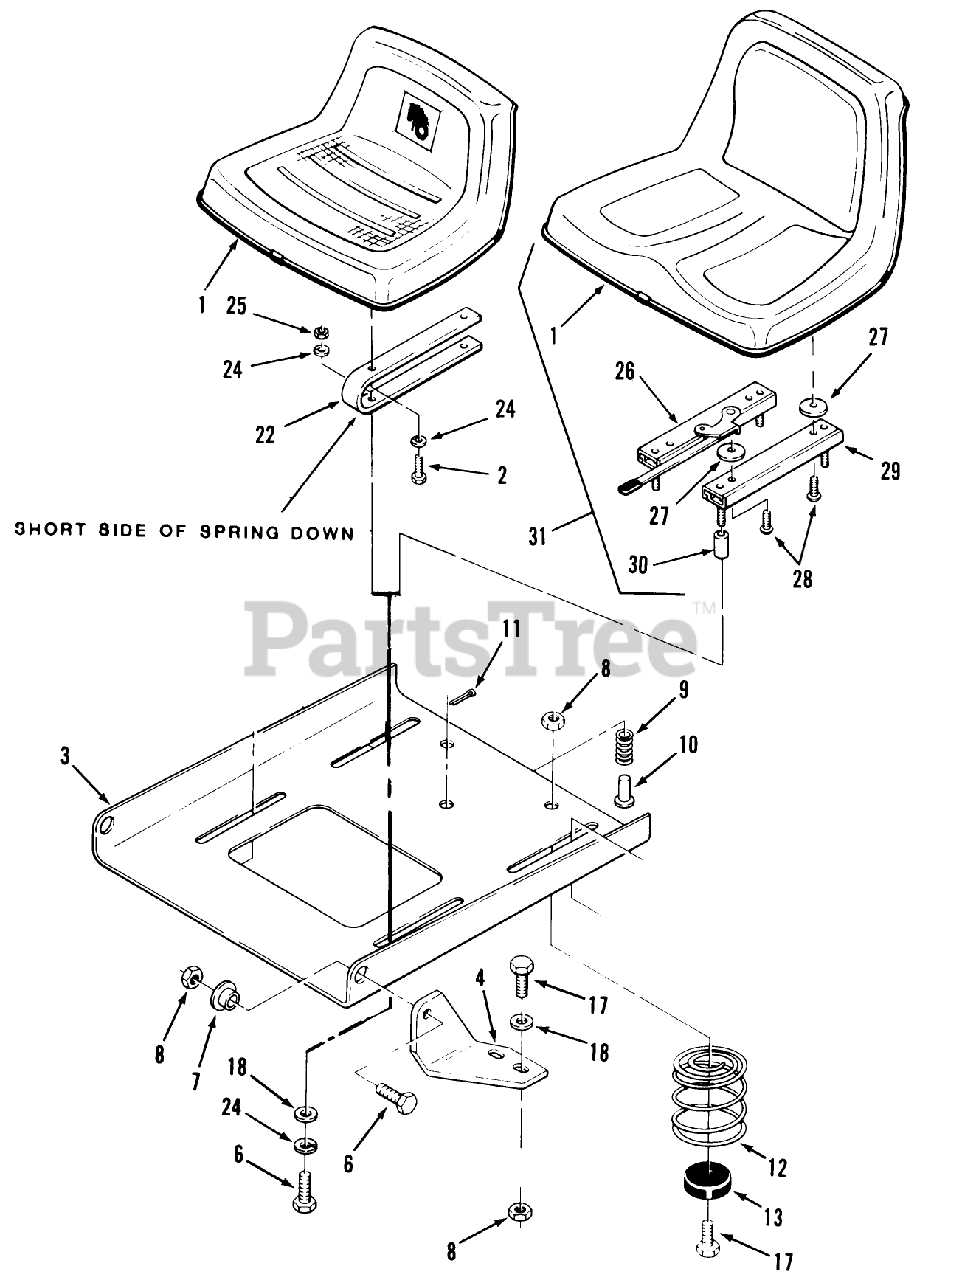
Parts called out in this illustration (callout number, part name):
4	BRACKET-PIVOT L.H *B
4	BRACKET-PIVOT R.H *B (NS)
7	BUSHING
9	SPRING-SEAT SWITCH
12	SPRING-SEAT NYLON
13	BUMPER
18	WASHER 5/16 SAE
27	SPACER-NYLON
